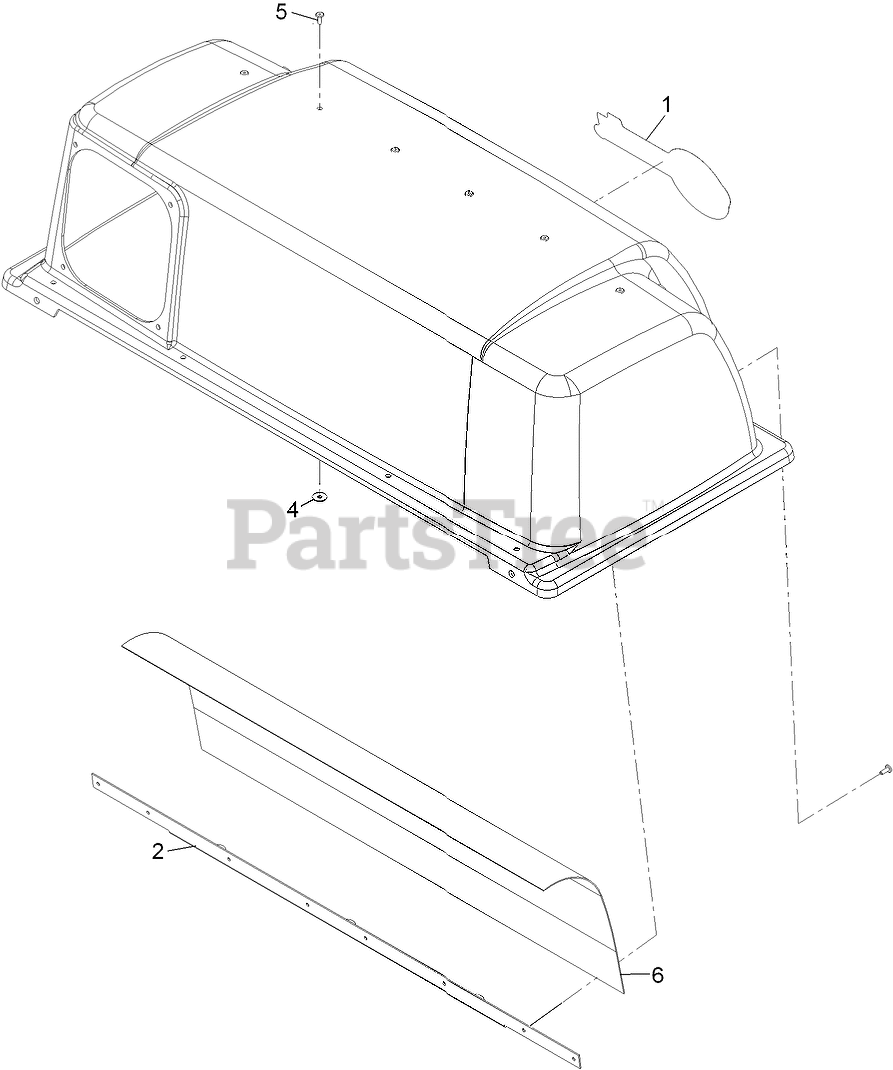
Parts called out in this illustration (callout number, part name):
1	DECAL-EXMARK LOGO
2	SUPPORT-SCREEN
4	WASHER-FLAT
5	RIVET-BLIND
6	SCREEN-BAGGER
